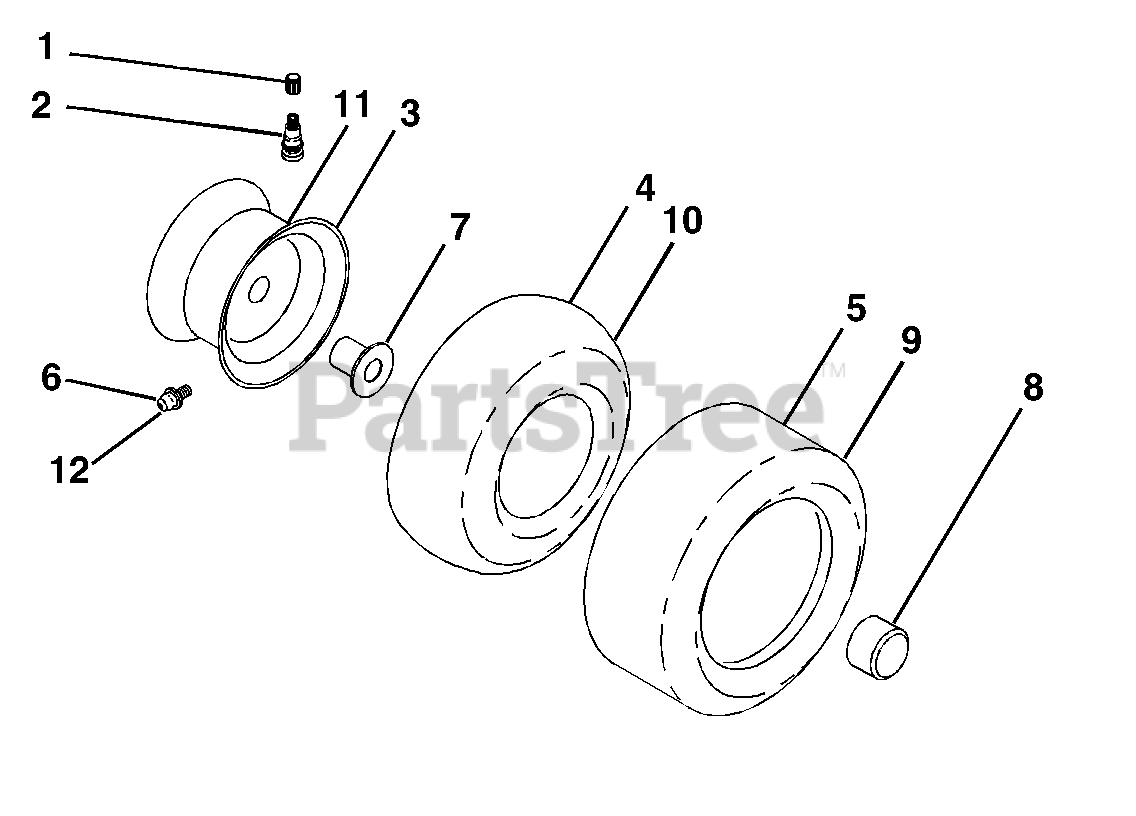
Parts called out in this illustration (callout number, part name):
1	Cap, Valve, Tire
2	Stem, Valve
3	Rim Assembly, Front
4	Tube, Front (Service Item Only)
5	Tire, Front
6	Fitting, Grease
7	Bearing, Flange (Front Wheel Only)
8	Cap, Hub
9	Tire, Rear
10	Tube, Rear (Service Item Only)
11	Rim Assembly, Rear
12	Fitting, Grease
